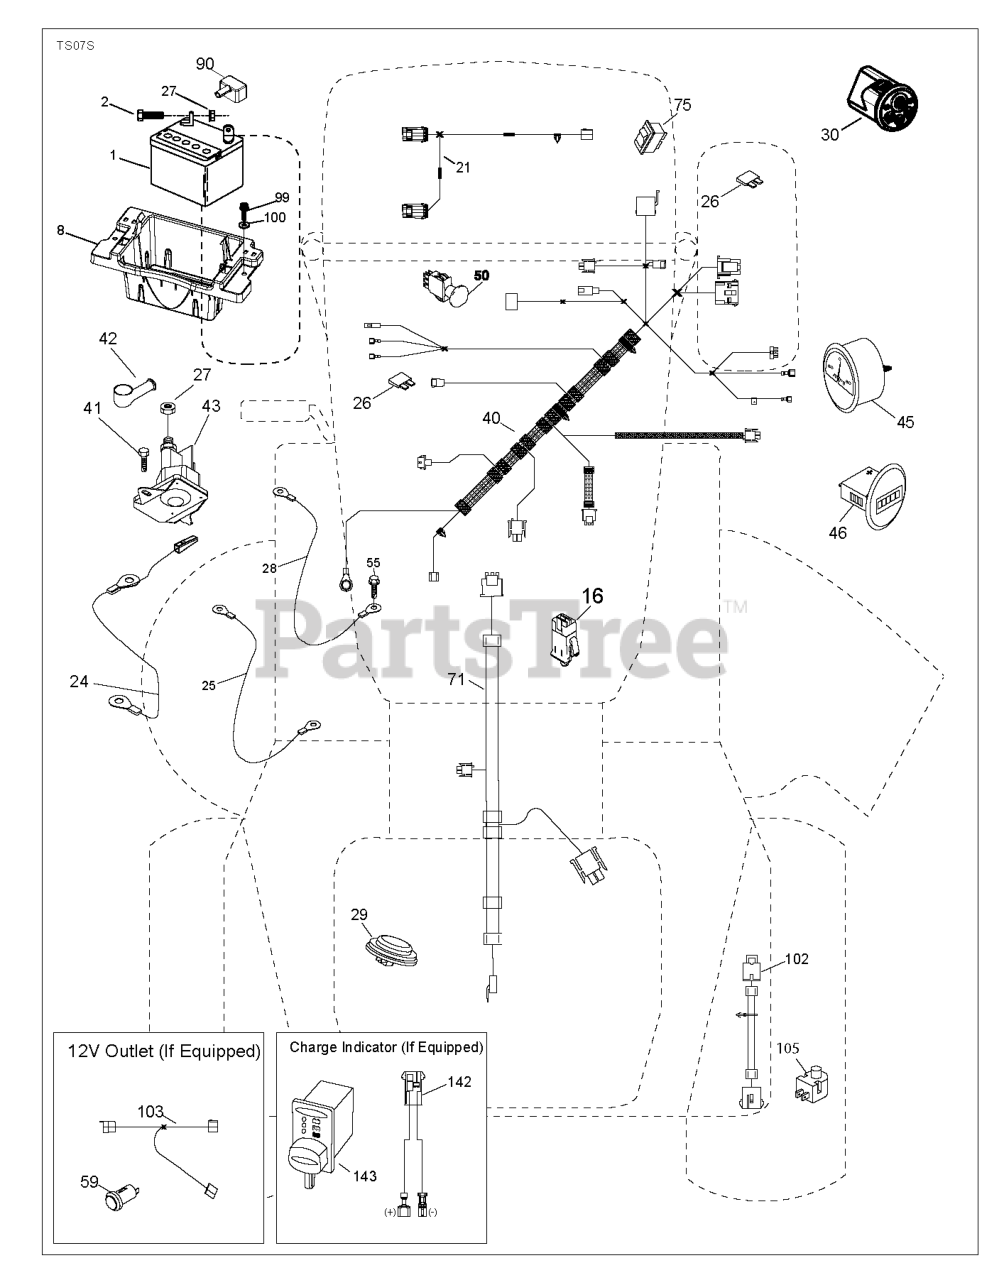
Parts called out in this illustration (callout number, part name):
1	Battery 12 Volt 25 Amp
2	BOLT.HEX.1/4.X.3/4.DICHROMATE
8	TRAY.BATTERY BOX.FRONT
16	SWITCH INTERLOOK PUSH-IN
21	HARNESS.LIGHT W/4152J BULBS
24	CABLE.BTRY.HARN.POS.LEAD
25	CABLE.STARTER.8GA.17.5
26	FUSE 20AMP
27	NUT
28	CABLE.GROUND.STARTER
29	SWITCH.SEAT.OPC.GRY.BUTTON/CAP
30	SWITCH.ASM.SMARTSWITCH.MY15.TR
40	HARNESS.DASH.EL.SIS.RND.MY15
41	SCREW
42	TERMINAL COVER
43	SOLENOID.STARTER.BRASS.PLUNGER
45	GAUGE.AMMETER.SILVER/WHITE
46	GAUGE.HOUR.METER.SILVER/WHITE
50	SWITCH.PTO.8TERMINAL.STD.BLK
55	SCREW 5/16"
59	OUTLET.12-VOLT
71	HARNESS CHAS.SMART.IGN
75	SWITCH.ON/OFF.(DIFF.LOCK)
90	COVER.TERMINAL.BATTERY
99	SCREW HEXWSHR 1/4-20X3/4
102	HARNESS PIGTAIL PCH TEX ROS
103	HARNESS.PIGTAIL.12V.OUTLET.
105	REVERSE SWITCH
142	CHARGE.PORT.PIGTAIL HARNESS
143	CHARGE.PORT
